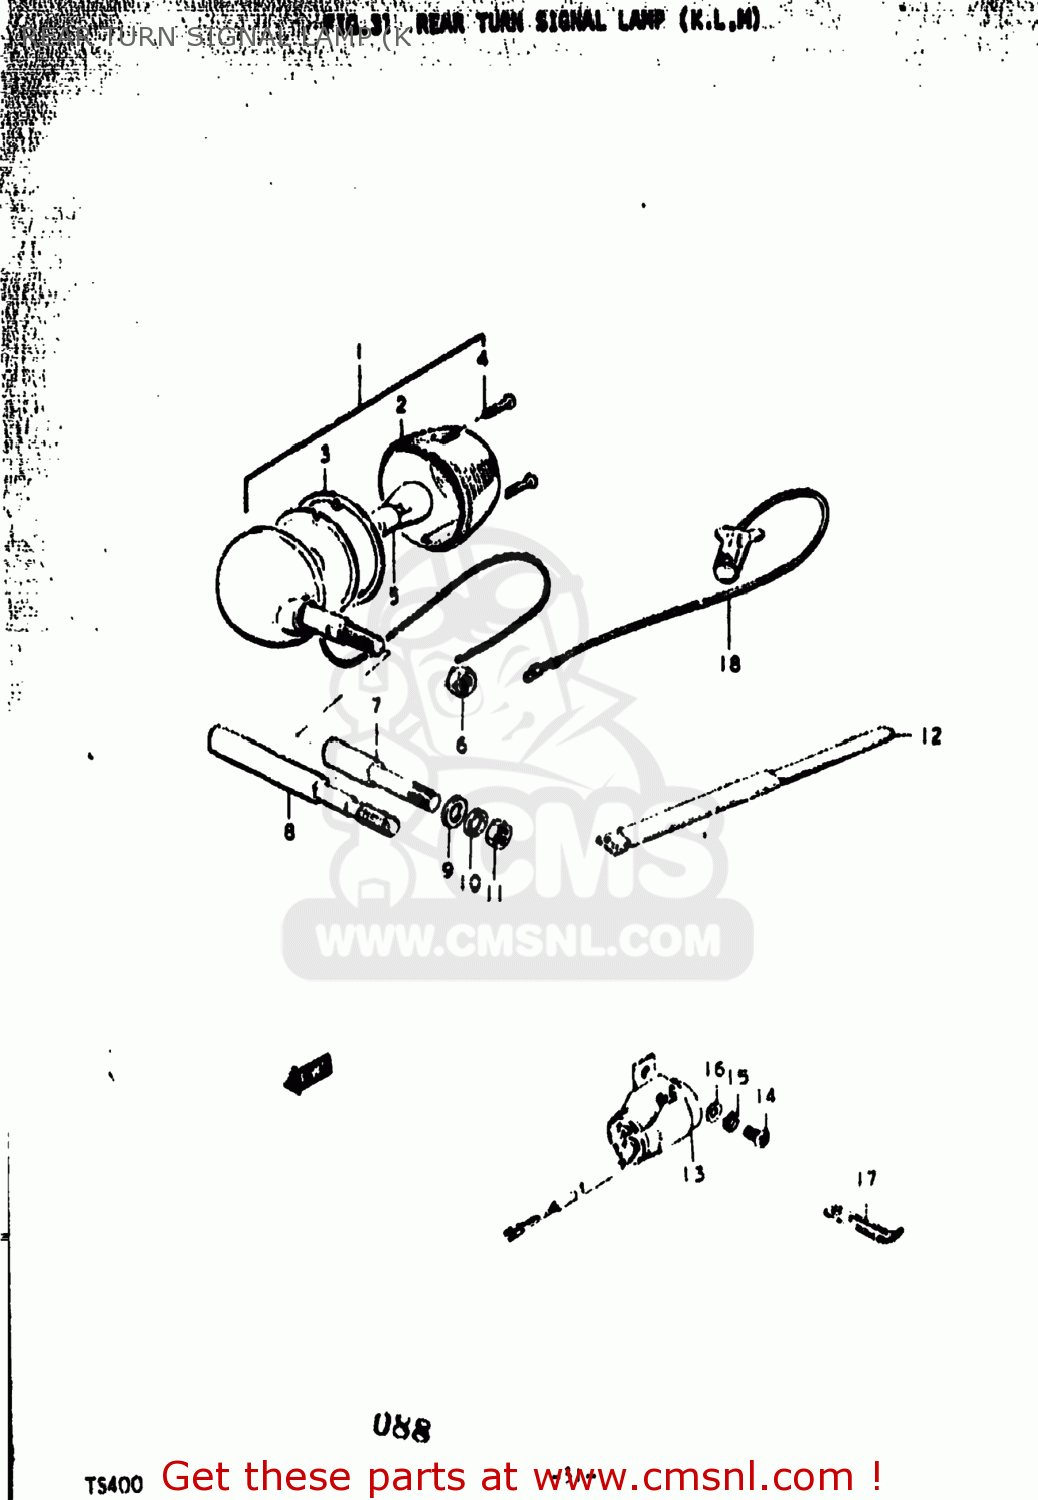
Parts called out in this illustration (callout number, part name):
1	LAMP ASSEMBLY,REAR TURN SIGNAL
2	LENS
3	GASKET,TURNSIGNAL LENS (NAS)
4	SCREW
5	BULB(12V23W,STANLEY,A4577A)
6	NUT
7	STAY,TURN SIGNAL,REAR
8	STAY,TURN SIGNAL,REAR
9	WASHER
10	LOCK WASHER
11	NUT
12	CLAMP
13	RELAY,TURN SIGNAL
14	SCREW
15	LOCK WASHER
16	WASHER
17	CLAMP L:35
18	WIRE
